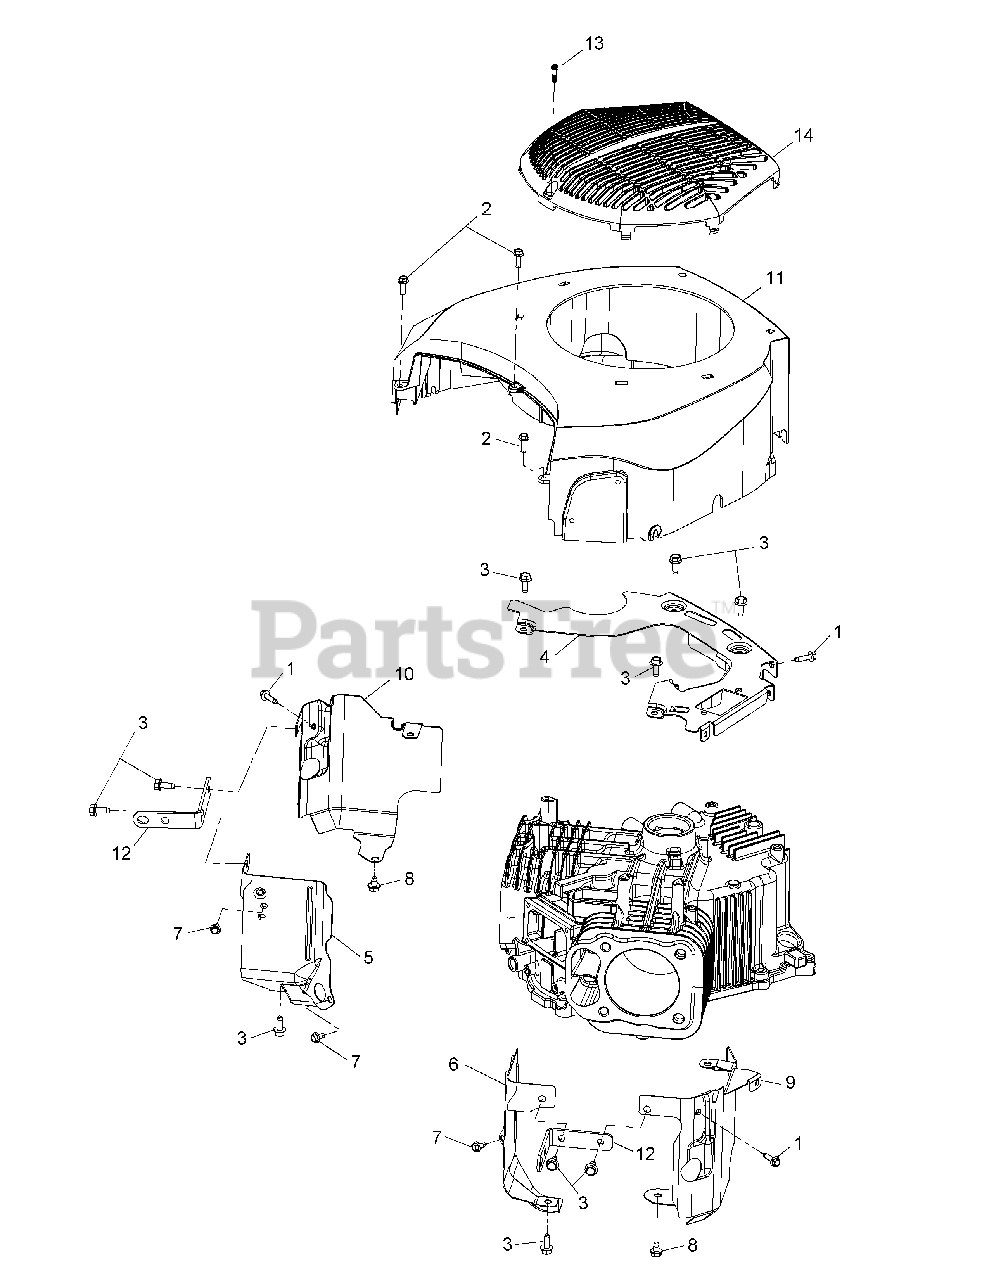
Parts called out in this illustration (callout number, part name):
1	Thread Forming Screw
3	Thread Forming Screw
4	Backing Plate
5	Valley Baffle, #1 Cylinder
6	Valley Baffle, #2 Cylinder
7	Thread Forming Screw
8	Thread Forming Screw
9	Left Barrel Baffle
10	Right Barrel Baffle
11	Blower Housing
13	Screw, M5-2.42
